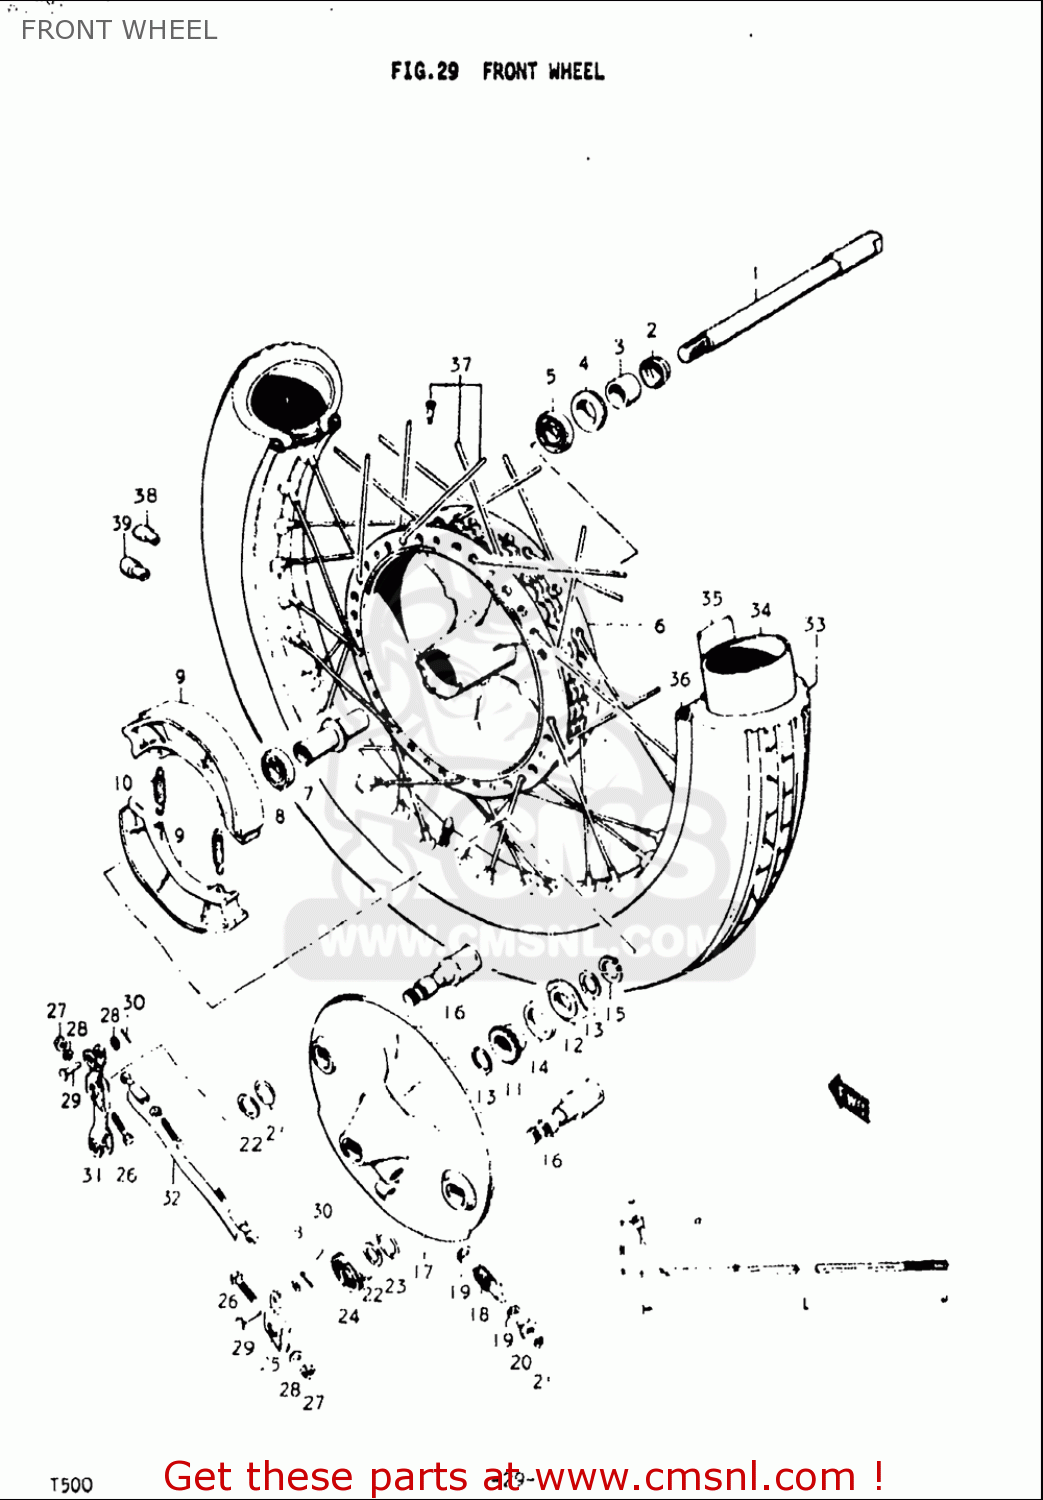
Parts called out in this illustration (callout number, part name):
1	AXLE,FRONT
3	SPACER
5	BEARING
7	SPACER,FRONT HUB BEARING
8	BEARING
9	SHOE SET,BRAKE (NAS)
10	SPRING,BRAKE SHOE
12	DRIVER,SPEEDOMETER GEAR
13	WASHER(22.5X27X1)
14	SEAL,OIL(26X38X4)
15	CIRCLIP
18	PINION,SPEEDOMETER
19	WASHER(5.1X9X0.4)
20	BUSHING,SPEEDOMETER PINION
21	SEAL,OIL(6X10X3)
22	WASHER(15.5X24X1.6)
23	O RING(D:2.4,ID:14.8)
24	SPRING
26	BOLT(6X31)
27	NUT
28	WASHER
30	PIN 12X10
34	TUBE ASSEMBLY,WHEEL,INNER
35	PROTECTOR,WHL INR TUBE
36	RIM,WHEEL
38	BALANCER,WHEEL (B)
39	BALANCER,WHEEL (30G)
